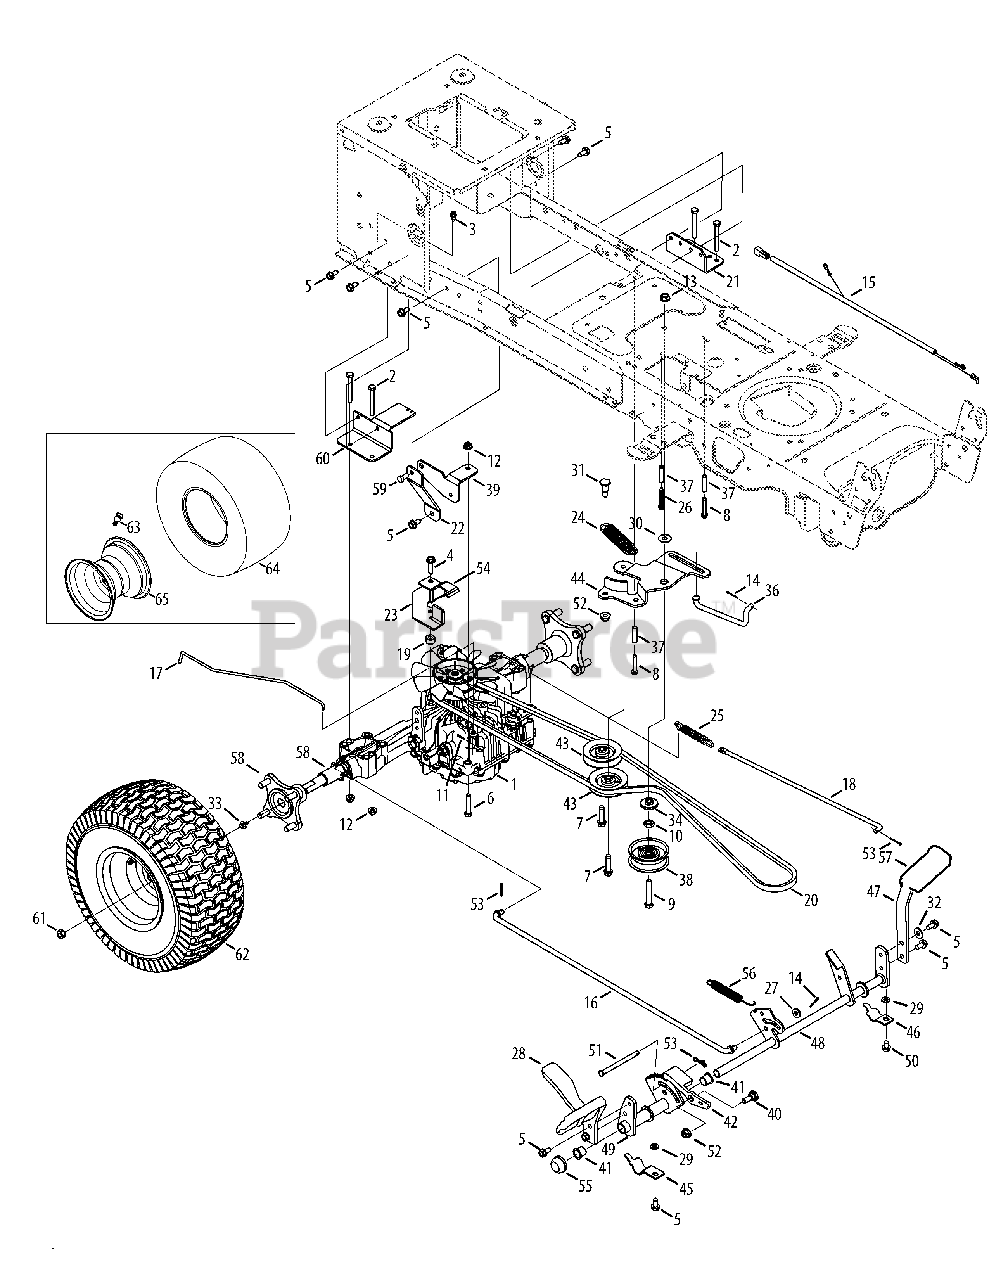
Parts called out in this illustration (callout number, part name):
1	Transmission, Tuff Torq K46
2	Hex Screw, 5/16-18, 2.50, Gr5, Std
3	Screw, Self-tapping, 1/4-20, 0.500
4	Screw, Self-tapping, 5/16-18, 1.250
5	Screw, Self-tapping, 5/16-18, .750
6	Hex Screw, 5/16-18, 1.75, Gr5
7	Screw, Self-tapping, 3/8-16, 1.500
8	Screw, Self-tapping, 1/4-20, 1.625
9	Hex Screw, 3/8-16, 2.25, Gr5
10	Nut, Jam, 7/16-20, Gr2
11	Pin, Cotter, 3/32, 1.0
12	Nut, Flange Lock, 5/16-18, Nylon
13	Nut, Flange Lock, 3/8-16
14	Pin, Cotter, 3/32, .625
15	Jumper Harness, Ground & Reverse
16	Rod, Control, Tuff-Torq
17	Rod, Hydro Bypass
18	Rod, Brake, NX9 Tuff-Torq
19	Spacer, .330 x .715 x .430
20	Belt, V-Type
21	Bracket, Mount, Tuff-Torq
22	Bracket, NX9 Tuff Torq
23	Bracket, Belt Keeper
24	Spring, Extension, 1.00 Dia x 4.75
25	Spring, Extension, .59 Od x 4.00
26	Screw, Self-tapping, 1/4-20 x 1.75
27	Washer, Flat, .375 x .738 x .063
28	Control Pedal
29	Washer, Flat, .344 x .688 x .065
30	Wash, Flat, .385 x 1.00 x .030
31	Scr, Shldr, .50 x .685 3/8-16
32	Washer, Bell, .340 x .872 x .060
33	Screw, 5/16-24 x .750
34	Spacer, Shoulder, 1.375 x .380 x .183
35	Wheel Hub Assembly
36	Rod, Transmission, Bypass
37	Spacer, .260 x .372 x 1.420
38	Pulley, Idler, Flat 2.75 OD
39	Bracket, Support
40	Bolt, Shoulder, .500 x .270, 3/8-16
41	Bearing, Flange, .630 x .695 x .60
42	Latch, Cruise
43	Pulley, Idler, V-Type x 3.06
44	Bracket, Idler, Center Double
45	Bracket, Support, Pedal Strap
46	Bracket, Support, Pedal Strap 5/8
47	Bracket, Pedal, Brake
48	Control Assembly, Brake
49	Bracket Assembly, Pedal, Hydro
50	Screw, Self-tapping, 5/16-18, 0.625,
51	Pin, Clevis, 5/16 x 3.985
52	Nut, Flange Lock, 3/8-16, Nylon
53	Pin, Cotter, Bow-Tie 72
54	Bracket, Belt
55	Cap, Push 5/8
56	Spring, Extension, .63 Dia x 4.95
57	Pad, Pedal, Brake
58	Sleeve, .765 Id x 2.11
59	Hex Cap Screw, 3/8-16 x .75
60	Bracket, Mount
62	Wheel Assembly
63	Tubeless Air Valve
65	Rim Assembly
